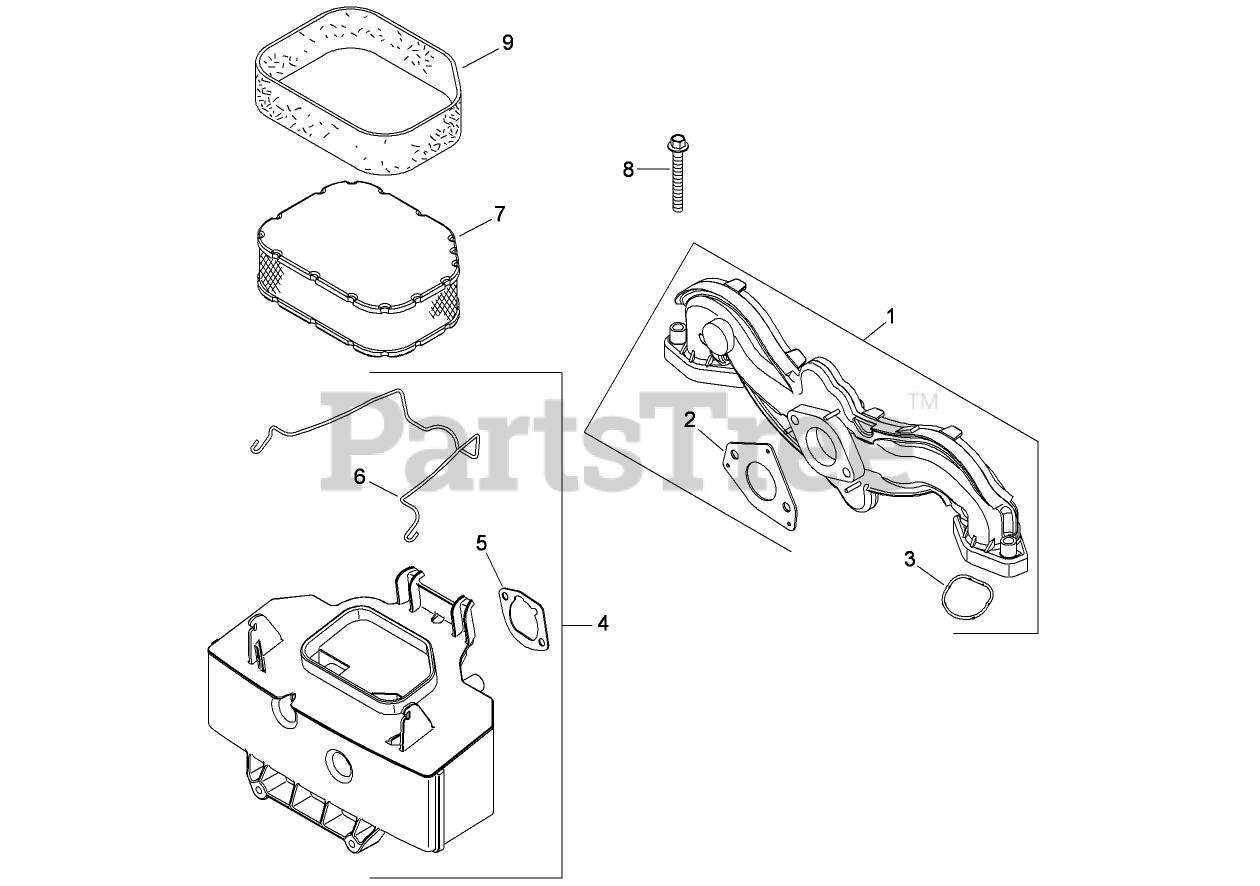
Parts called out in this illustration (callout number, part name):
1	Manifold-Intake (Includes 2-3)
2	GASKET-CARBURETOR
3	O-RING
4	AIR CLEANER BASE KIT (INCLUDES 5-6)
5	GASKET-BASE, AIR CLEANER
6	LATCH-ELEMENT, AIR CLEANER
7	ELEMENT-FILTER, AIR
8	SCREW-FLANGE (M6X1.0X40)
9	ELEMENT-CLEANER, PRE
